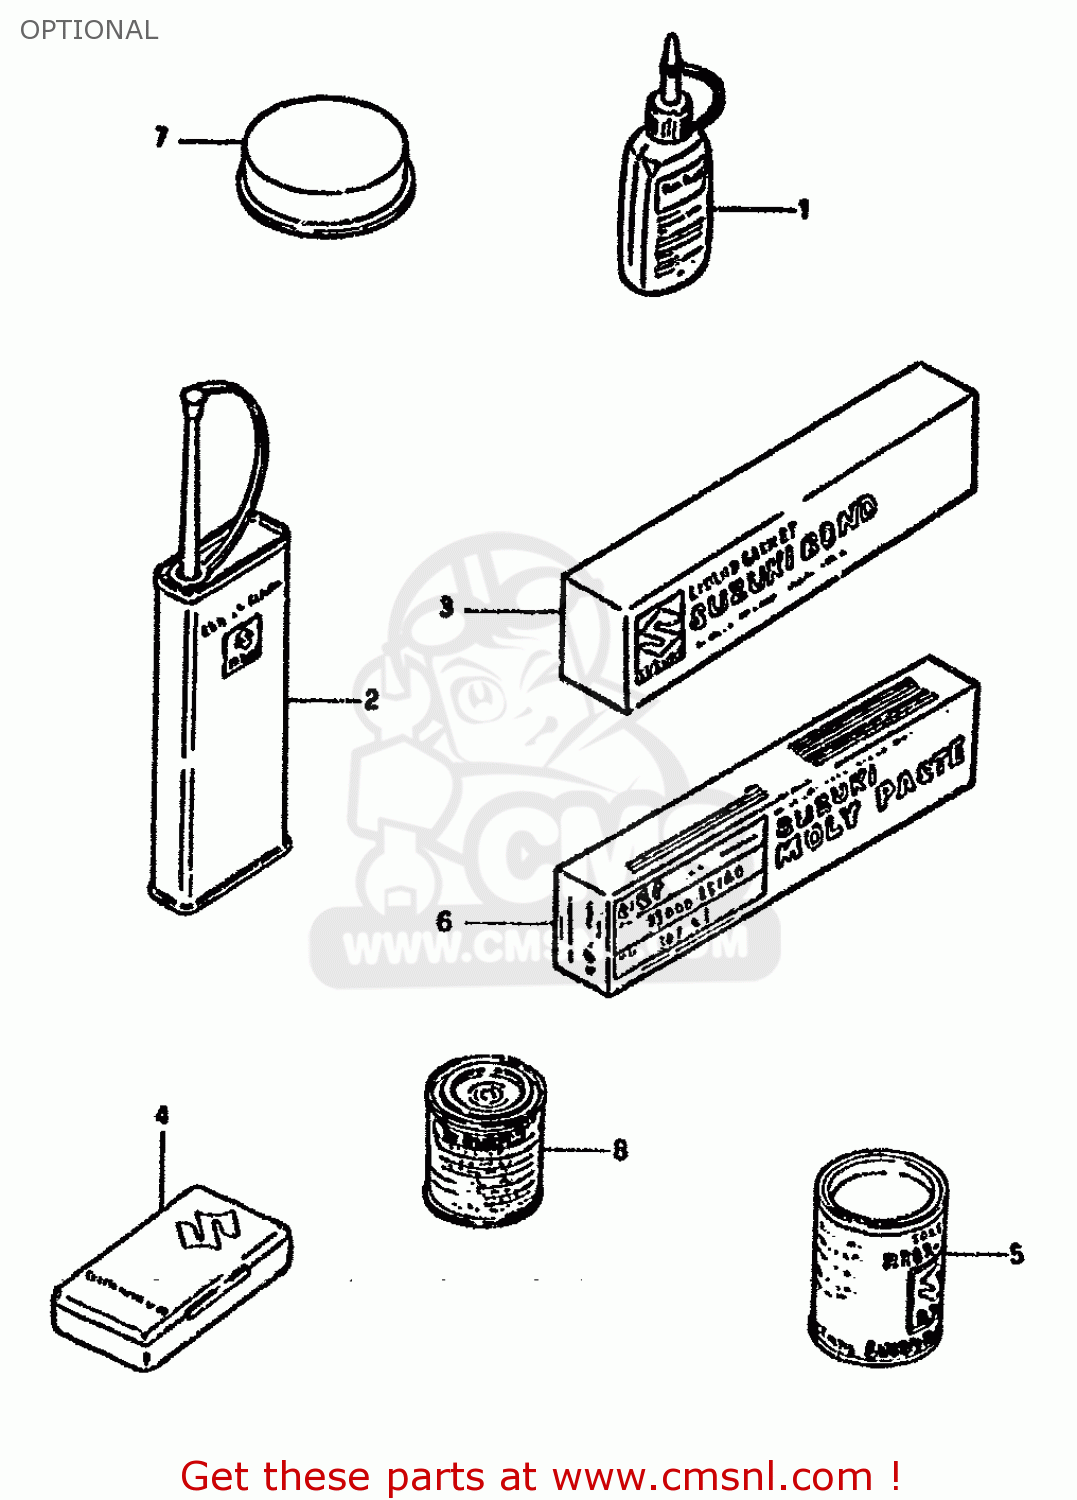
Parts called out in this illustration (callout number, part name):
1	THREAD LOCK NO.1342
2	THREAD LOCK NO.1401 CLEAR 200G
3	LIQUID GSKT NO.1207B 100G BLK
4	TUBE REPARING TOOL
5	GREASE(C)EP2 LITHIUM 150G
6	SUZUKI MOLY PASTE
7	GREASE,PBC FOR BRK PAD 20G
8	PAINT,BLACK
